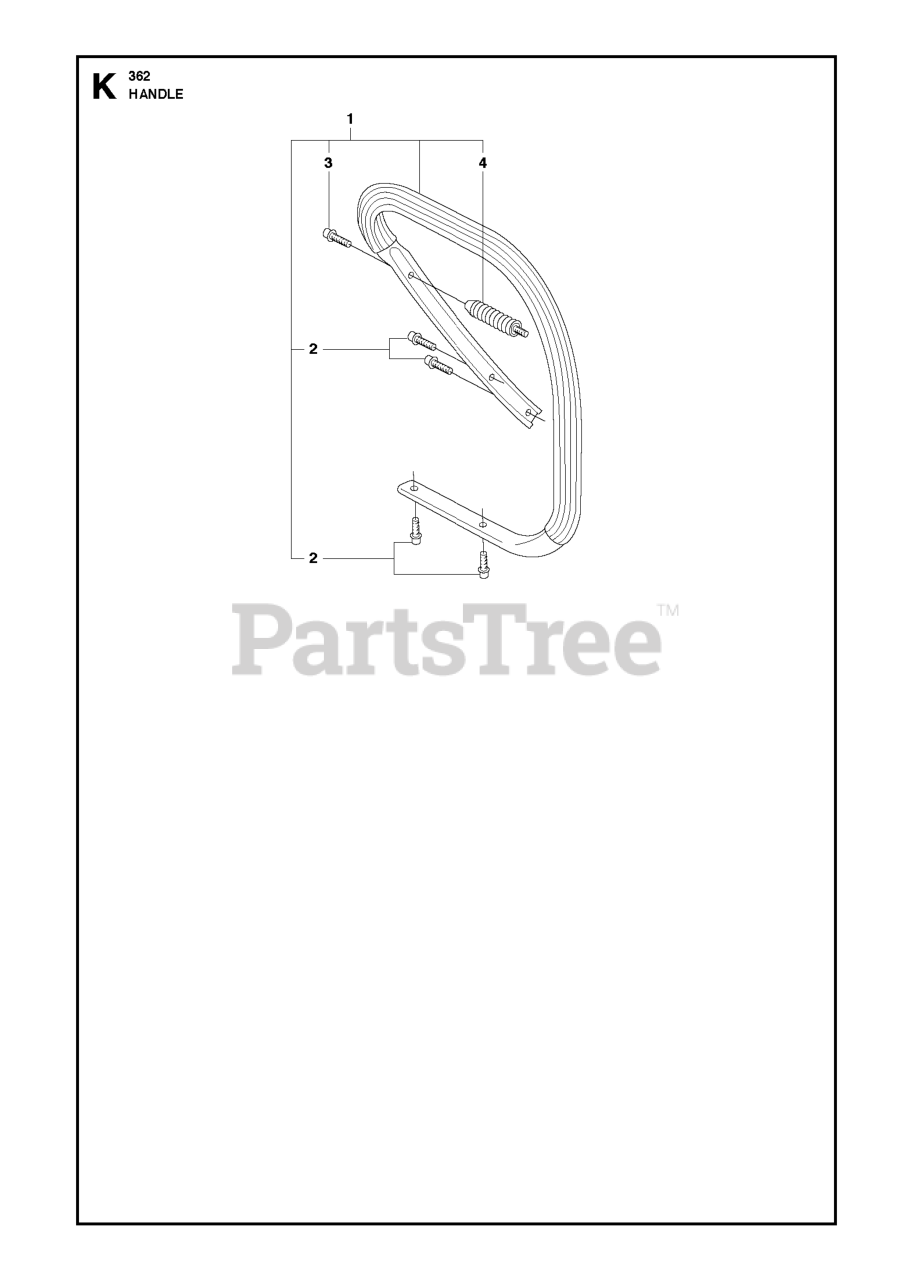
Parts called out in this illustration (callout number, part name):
1	FRONT HANDLE
2	SCREW IHSCFT PW5.5X16 8.8 ZN/
4	VIBRATION ABSORBER
4	ANTIVIBE MOUNT
